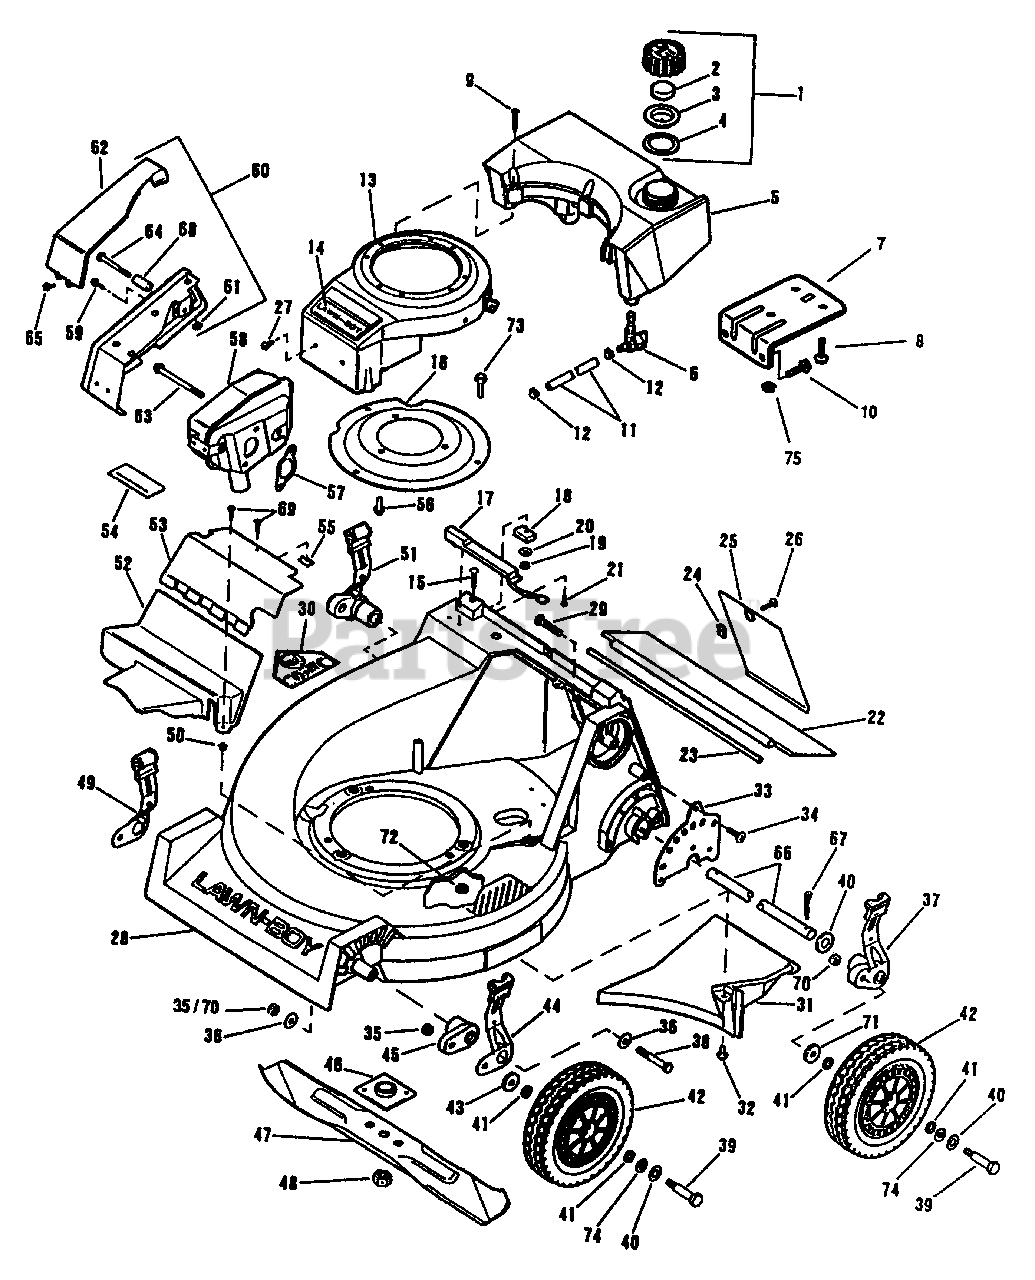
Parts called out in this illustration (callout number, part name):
1	Fuel Cap Assembly
2	Baffle
3	Cover
4	Gasket
5	Fuel Tank
6	Fuel Shut-off Valve
7	Fuel Tank Mounting Bracket
8	Screw
9	Screw-Fuel Tank
10	Screw-Fuel Tank Bracket to Block
11	Fuel Line
12	Clamp-Fuel Line
13	Shroud and Applique Assembly
14	Applique
15	Screw-Magnet to Housing (ZPRB & D)
16	Engine Mounting Plate
17	Switch Assy-Bag Lock (ZPRC & D)
18	Magnet Assembly
19	Nut-Magnet to Housing
20	Lockwasher-Magnet to Housing
21	Screw-Bag Lock Switch to Housing
22	Trailing Shield
23	Rod-Trailing Shield
24	Speed Nut
25	Access Door
26	Screw
27	Screw-Shroud
28	Housing Assy (ZPRB & D)
29	Handle Mounting Bolt
30	Decal-Blade Contact Warning
31	Baffle-Chute Floor
32	Screw
33	Height Adjust Plate
34	Screw
35	Nut-Front Wheel Bolt (ZPRC & D)
36	Washer-Front Height Adjust Arm
37	Height Adjust Arm Assembly-L.H.
38	Screw-Front Height Adjust Arm
39	Bolt-Wheel
40	Washer
41	Felt Washer
42	Wheel and Tire Assembly
43	Washer
44	Knob and Spring Assy-Front L.H.
45	Front Height Adj Arm (ZPRB & D)
46	Collar and Plate
47	21" Blade
48	Nut-Blade
49	Knob and Spring Assy-Front R.H.
50	Grommet
51	Height Adjust Arm Assembly-R.H.
52	Lower Drive Cover
53	Upper Drive Cover w/Decal
54	Decal-Warning
55	Speednut
56	Screw-Mounting Plate to Engine
57	Exhaust Gasket
58	Muffler
59	Screw-Muffler Guard
60	Muffler Guard Assembly
61	Pushnut
62	Muffler Cover
63	Screw-Muffler
64	Screw-Muffler Guard
65	Screw-Muffler Guard
66	Rod-Height Adjust
67	Cotter Pin
68	Spacer-Muffler Guard
69	Screw-Drive Cover to Housing (ZPRC & D)
70	Nut (ZPRC & D)
71	Washer-Flat
72	Locknut-Mting Plate to Housing
73	Screw-Mting Plate to Housing
74	Washer
75	Nut-Hex Flange
